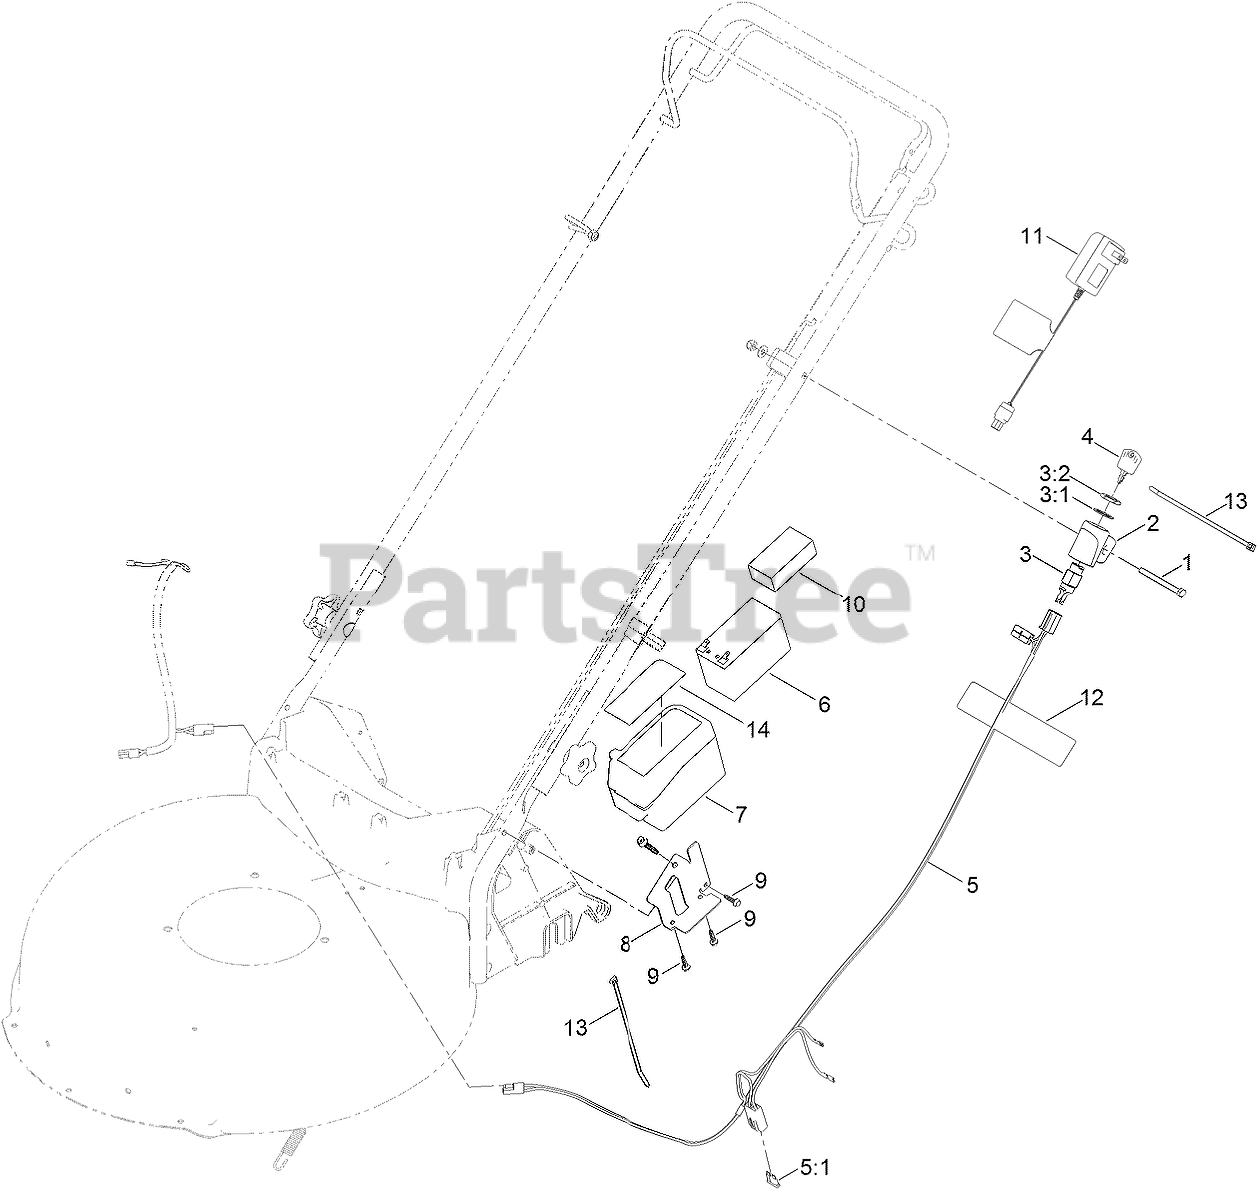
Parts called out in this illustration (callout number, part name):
1	SCREW-HH
2	MOUNT-SWITCH
3	STARTER SWITCH ASM
3:1	WASHER-LOCK
3:2	NUT-HH
5	HARNESS-WIRE
5:1	FUSE-40 AMP
6	BATTERY-NONSPILLABLE, 12 V
7	BATTERY BOX ASM
8	BRACKET-BATTERY
9	SCREW-HWH
10	FOAM-BATTERY, TOP
11	CHARGER-BATTERY
12	DECAL-WARNING
13	TIE-CABLE
14	DECAL-BOX, BATTERY
